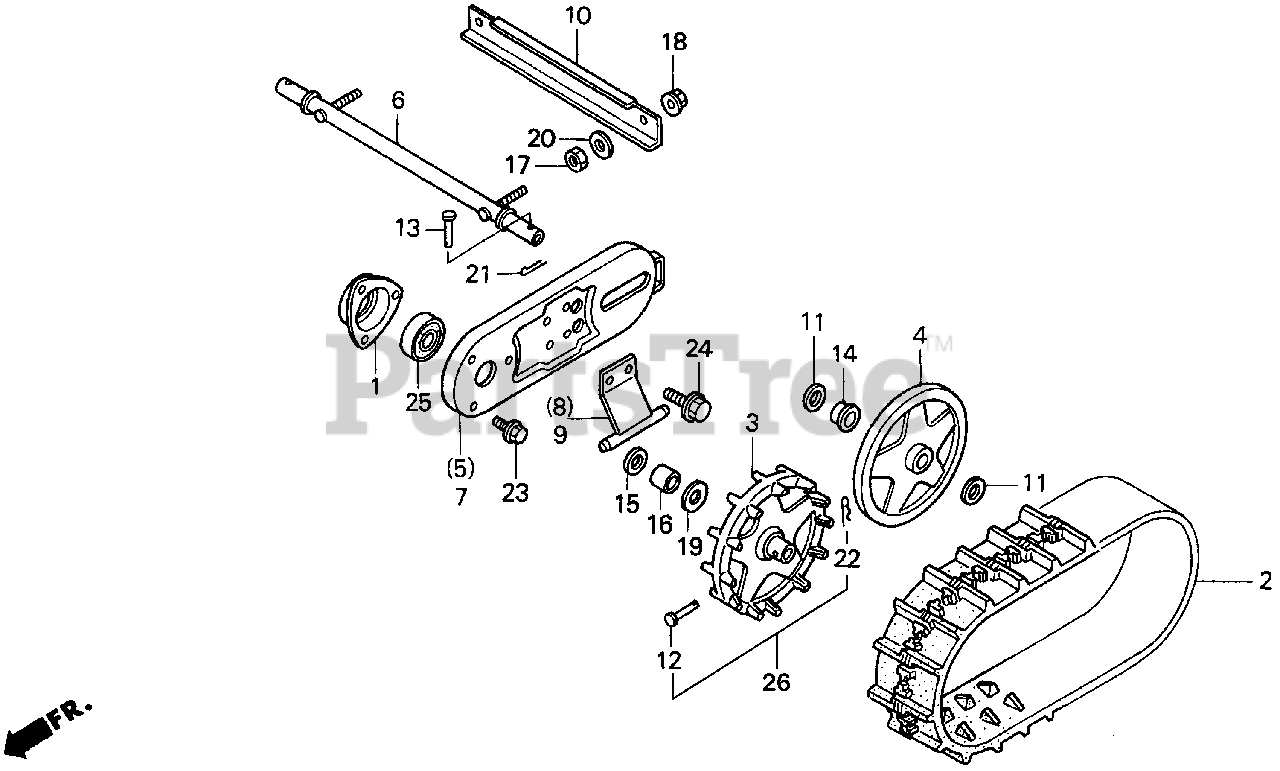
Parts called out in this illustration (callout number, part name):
1	HOLDER, WHEEL SHAFT BEARING
2	CRAWLER (12-60X20 B-122)
3	SPROCKET, CRAWLER
4	ROLLER, CRAWLER (COO)
5	PLATE, R. CRAWLER
6	PIPE, CRAWLER
7	PLATE, L. CRAWLER
8	GUIDE, R. CRAWLER
9	GUIDE, L. CRAWLER
10	BAR, CRAWLER PLATE
11	WASHER, PLAIN (22MM)
14	COLLAR, CRAWLER PIPE
15	COLLAR, R. WHEEL SHAFT
16	COLLAR, CRAWLER SPROCKET
17	NUT, HEX. (10MM)
18	NUT, FLANGE (10MM)
19	WASHER, PLAIN (20MM)
20	WASHER, PLAIN (10MM)
21	PIN, SPLIT (3.0X18)
22	PIN, SPLIT (3.0X18)
22	PIN, LOCK (6MM)
23	BOLT, FLANGE (6X12)
24	BOLT, FLANGE (8X14)
25	BEARING, RADIAL BALL (6004UU)
